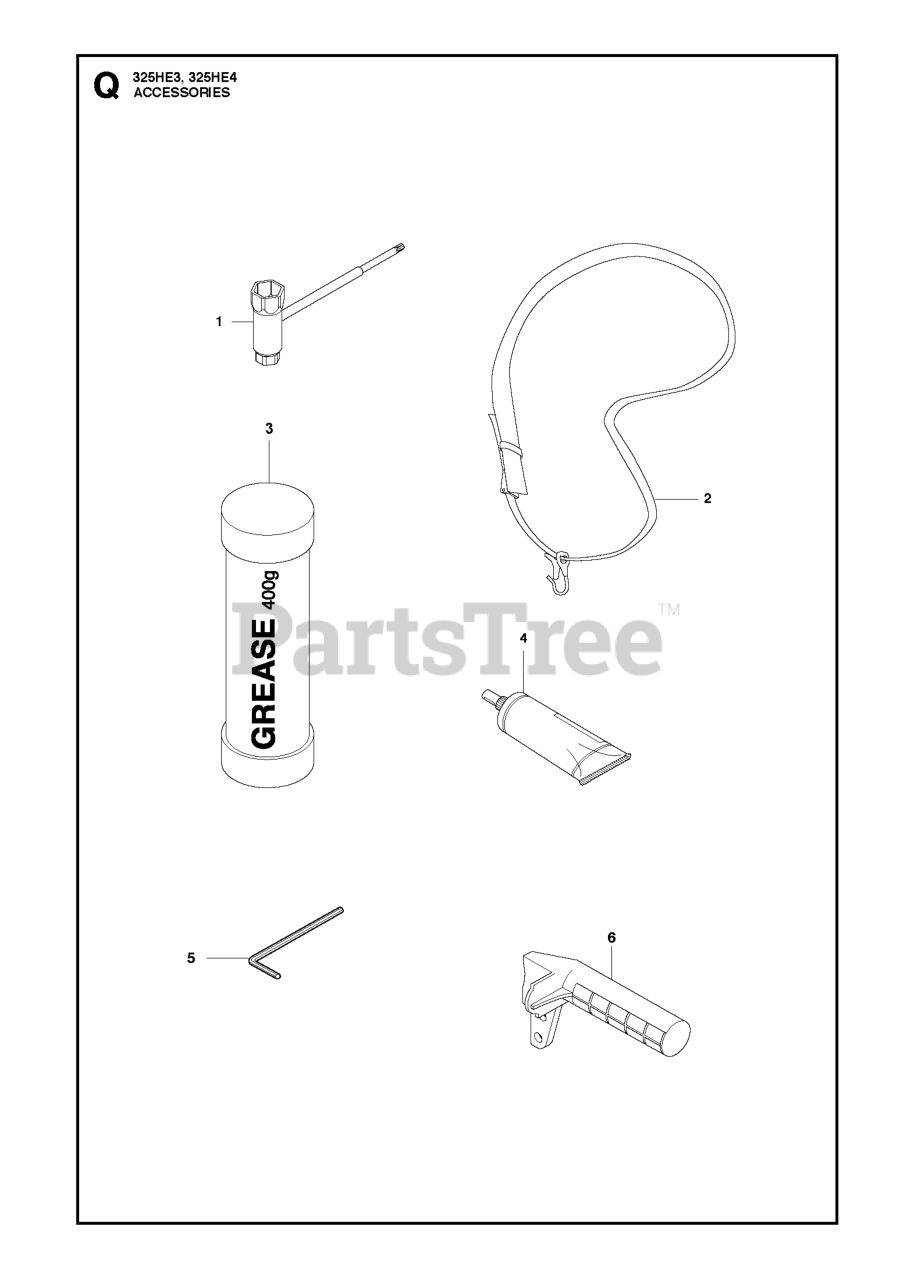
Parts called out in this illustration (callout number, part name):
1	COMBINATION WRENCH TORX
2	Harness-w/o warning
3	HUS MULTI ADVANCE GREASE 400GR
4	GREASE AS ACCESSORY
